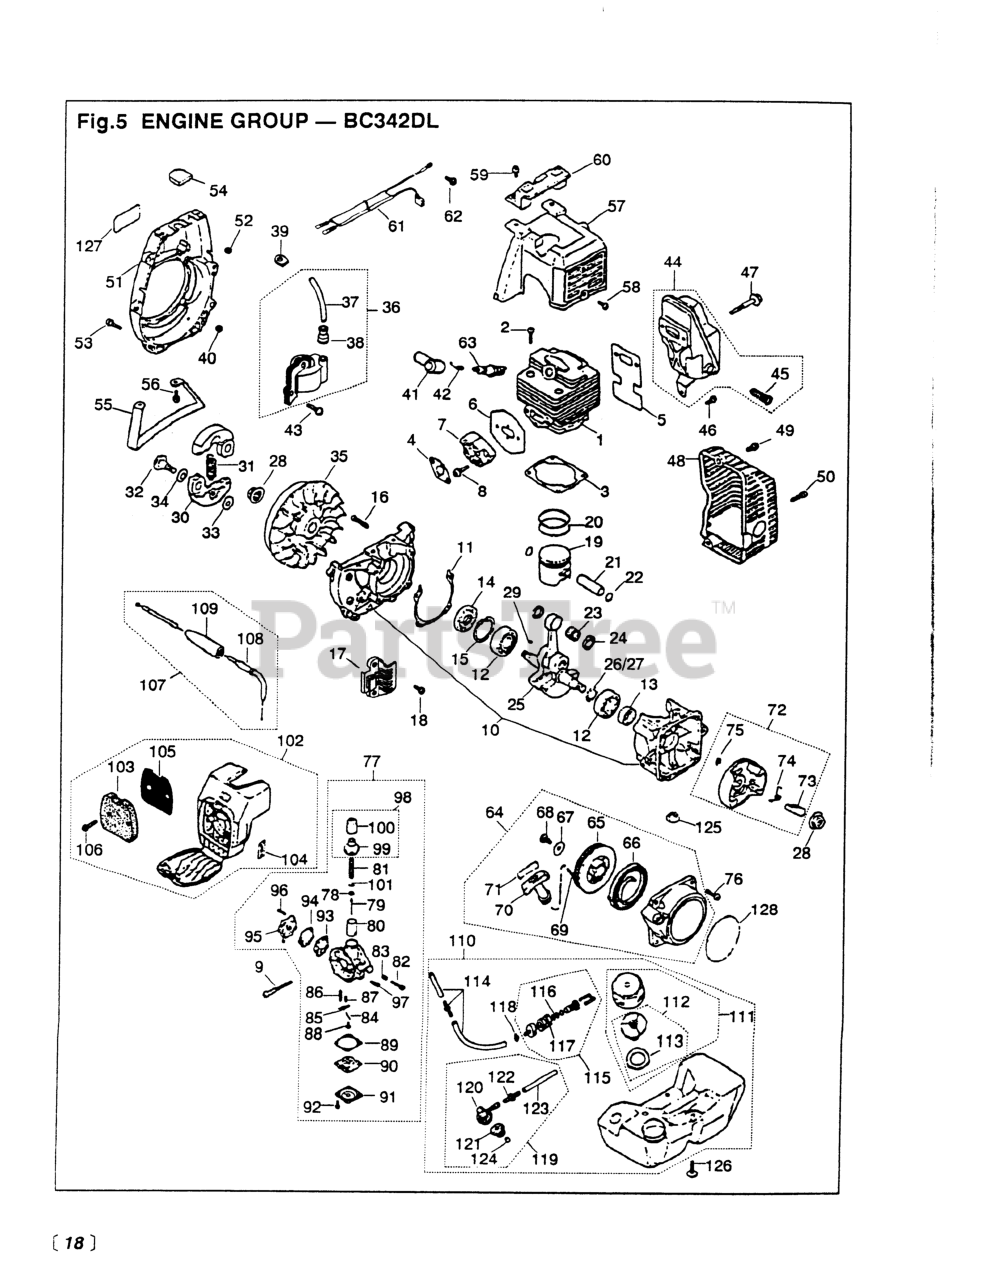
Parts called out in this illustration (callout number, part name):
3	GASKET
7	INSULATOR
8	SCREW, M5X20 (RPLS.1400-75510)
9	SCREW, M5 x 45
10	CRANKCASE (RPLS -21101)
14	SEAL, OIL (RPLS 1200-21220)
15	RING, SNAP, M32 x 1.2
16	BOLT, M5 X 30
18	SCREW,M5 X 14 (RPLS 1400-15510
20	RING, PISTON
21	PIN
22	RING, SNAP
23	BEARING
24	WASHER (RPLS 3310-41341)
25	CRANKSHAFT CO
26	SHIM (NO LONGER AVAILABLE)
29	KEY
31	SPRING, CLUTCH
32	SCREW
33	WASHER
36	COIL ASSEMBLY
38	CAP
39	GROMMET
42	SPRING
44	MUFFLER ASSEMBLY
45	ARRESTER
46	SCREW, M5 X 12
48	COVER, MUFFLER
50	BOLT
51	COVER, FAN
56	BOLT (REPLACES 01252-30514)
58	SCREW, M5 X 12
59	SCREW, M5X20 (RPLS.1400-75510)
60	HEAD GUARD
62	SCREW, M5 X 12
64	RECOIL ASSEMBLY
65	REEL
66	SPRING, SPIRAL
68	SCREW (RPLS -75150)
70	KNOB
72	PULLEY ASSEMBLY
73	RATCHET
74	SPRING, RETURN
75	E-RING
76	SCREW, M5X20 (RPLS.1400-75510)
78	RETAINER SPRING
82	SCREW (RPLS -81161)
85	ARM, FLOAT
86	VALVE (USE -81211)
87	SPRING, INLET
88	SCREW, FLOAT
89	GASKET (NLA)
90	DIAPHRAGM
92	SCREW, M3 X 8
93	GASKET, PUMP
94	DIAPHRAGM
95	COVER ASSY PU
96	SCREW, M3 x 12
97	NEEDLE (NLA)
99	CAP, MIXING
100	SEAL, AIR
102	CLEANER ASSY (USE -82002)
103	ELEMENT
104	LABEL
106	SCREW, M4 X 22
107	CABLE ASSEMBLY (NLA)
108	CABLE COMPLETE (NLA)
109	PROTECTOR
110	TANK ASSEMBLY (USE -85003)
112	VALVE COMPLETE
113	PACKING (RPLS -85321)
114	PIPE ASSEMBLY
115	FILTER ASSY
118	CLIP (REPLACES 2841-31280)
125	WASHER
126	SCREW, M5 X 22
128	LABEL BC342DL (RPLCS. -75411)
